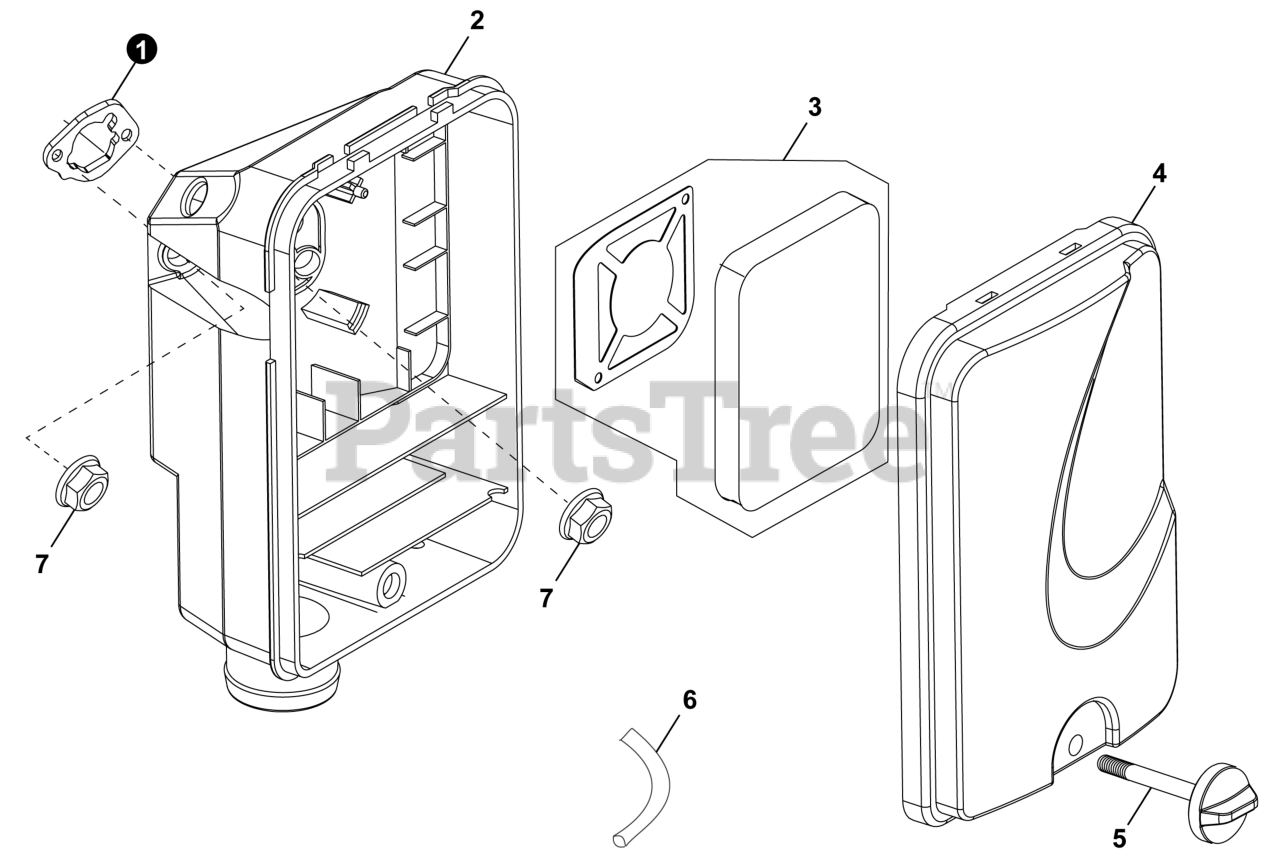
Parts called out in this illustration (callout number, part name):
1	GASKET, AIR CLEANER
2	HOUSING, AIR CLEANER
3	FILTER, AIR
4	COVER, AIR CLEANER
5	NUT, WING
6	TUBE, OIL DRAIN
